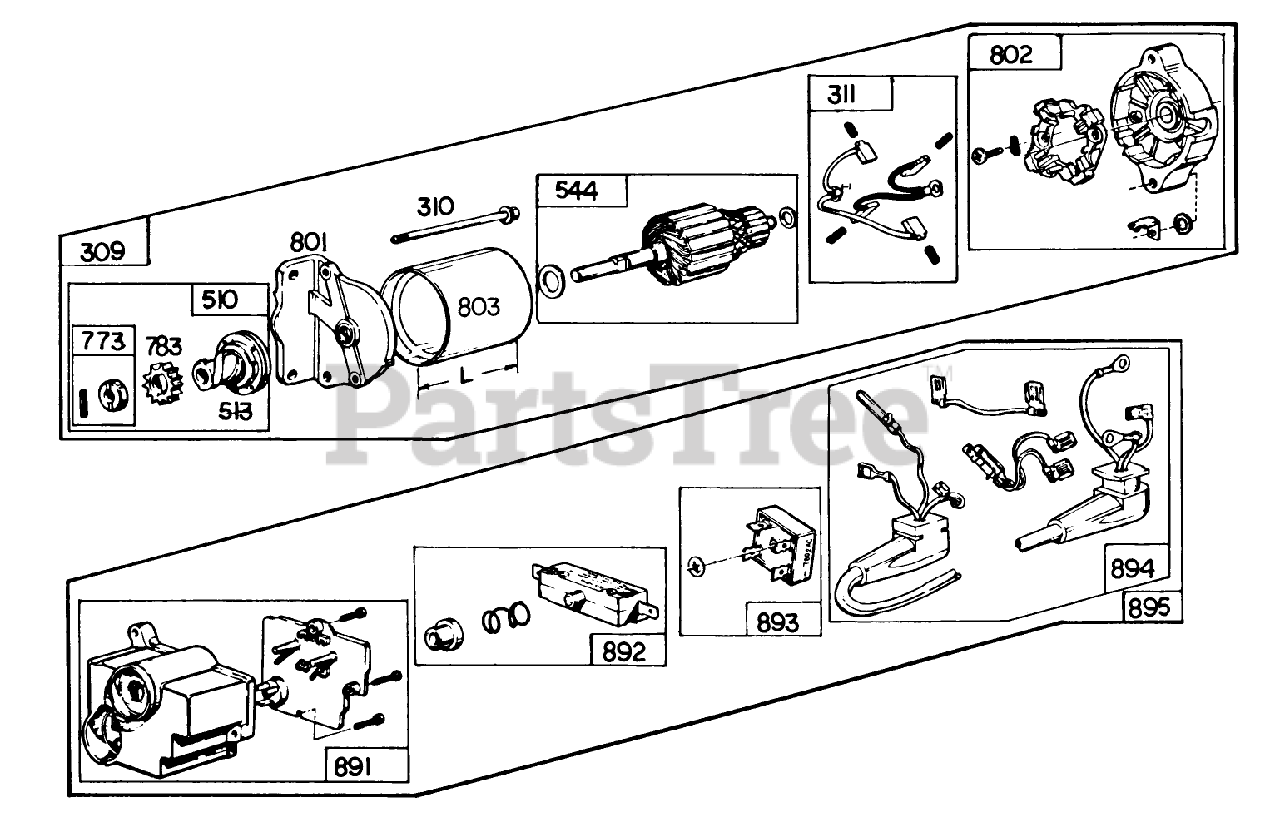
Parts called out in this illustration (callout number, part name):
309	Motor Drive Assembly
310	Thru Bolt Assembly
311	Brush Assembly
510	Drive Assembly
513	Clutch Assembly
544	Armature Assembly
773	Gear-Starter
801	Drive End Cap Assembly
802	Comm. End Cap Assembly
803	Housing Assembly
891	Housing Group
892	Switch Group
893	Rectifier
894	Lead Group
895	Control Group
